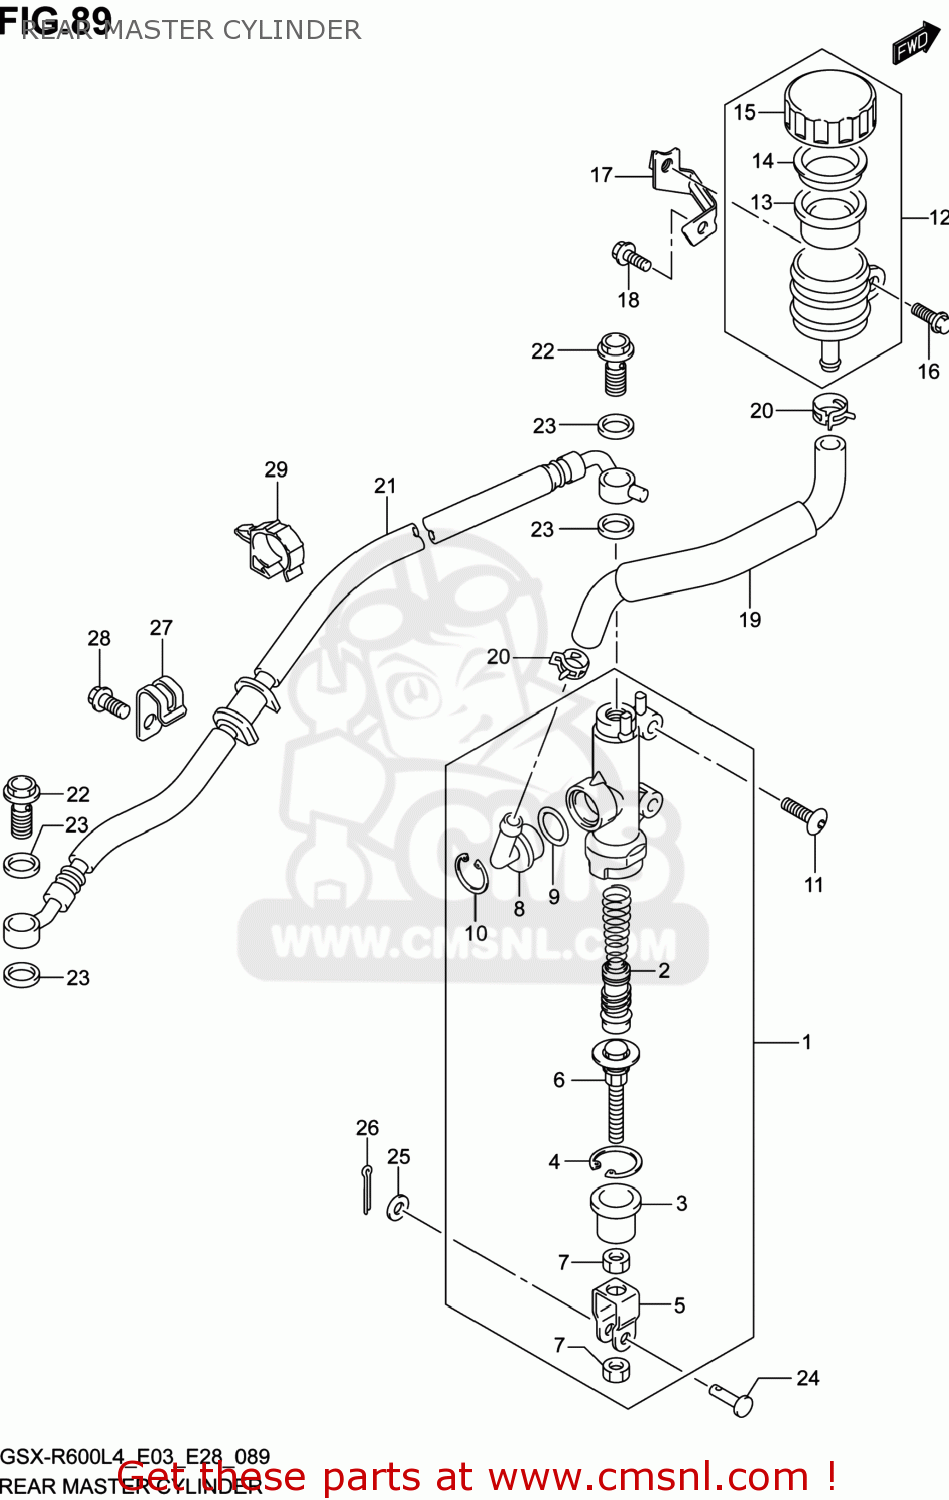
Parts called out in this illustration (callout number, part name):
1	CYLINDER ASSY,RR MASTER
2	PISTON/CUP SET
3	BOOT
4	CIRCLIP
5	YOKE
6	ROD,PUSH
7	NUT
8	CONNECTOR
9	O RING
10	CIRCLIP
11	SCREW(6X20)
12	TANK ASSY,RR RESERVOIR
13	DIAPHRAGM
14	PLATE
15	CAP
16	BOLT
17	BRACKET,RR RESERVOIR TANK
18	BOLT
19	HOSE,RR RESERVOIR TANK
20	CLIP
21	HOSE,RR BRAKE
22	BOLT UNION
23	WASHER(10X15X1.5)
24	PIN(6X18.2)
25	WASHER
26	PIN
27	CLAMP,RR BRAKE HOSE
28	BOLT
29	CLAMP
